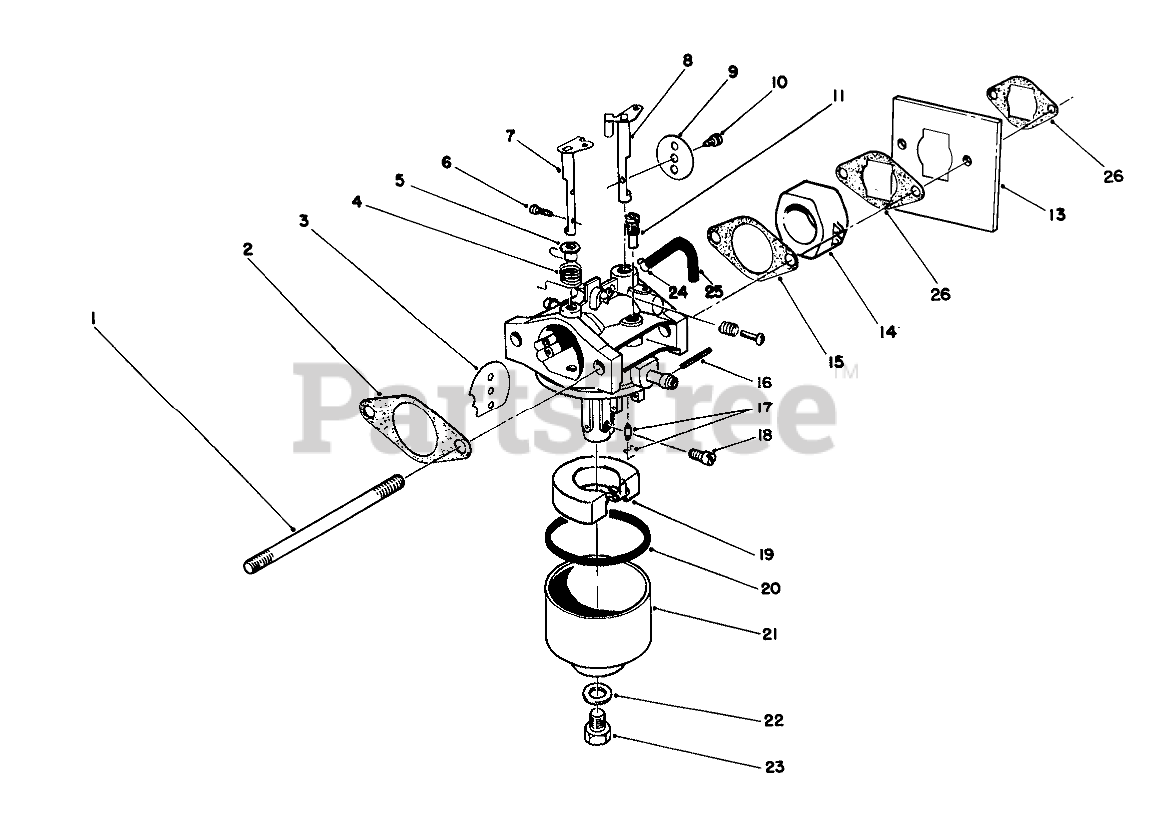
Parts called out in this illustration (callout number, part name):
1	STUD-CARBURETOR
2	GASKET-AIR CLEANER
3	PLATE
4	SPRING
5	BUSHING
6	SCREW
7	SHAFT-CHOKE
8	SHAFT
9	PLATE
10	Screw-Throttle
11	PILOT JET
13	SHIELD-CARBURETOR
14	INSULATOR-CARBURETOR
15	GASKET-CARB
16	Pin
17	NEEDLE
18	JET-MAIN
19	FLOAT
20	GASKET
21	BOWL - FLOAT
22	GASKET
23	SCREW
24	CLAMP
25	VENT TUBE
26	GASKET
